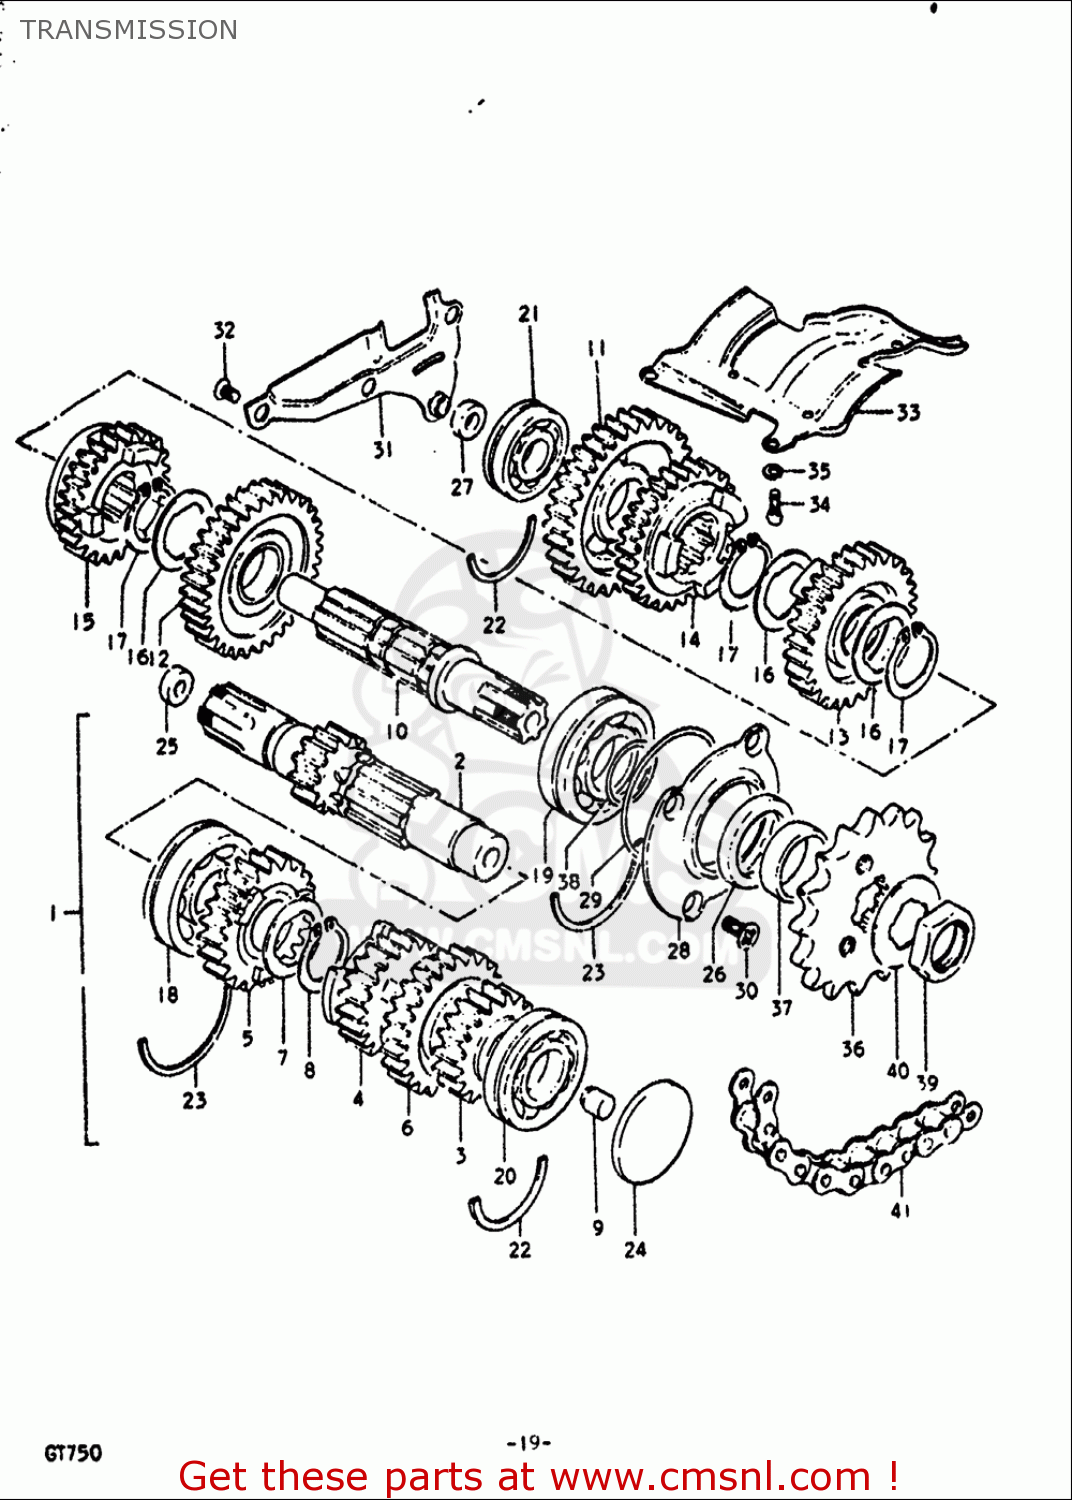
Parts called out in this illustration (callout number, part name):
7	WASHER,LOCK
8	CIRCLIP
9	PLUG
16	WASHER,LOCK
17	CIRCLIP
19	BEARING
20	BEARING(20X47X14)
22	C RING
25	SEAL,OIL (10X17X5)
26	SEAL,OIL(32X42X6)
27	SEAL,OIL(8X14X4)
29	O RING(D:2,ID:64.5)
30	SCREW
32	SCREW
34	SCREW
35	WASHER,LOCK
36	SPROCKET,ENGINE
37	SPACER(25X32X10.7)
38	O RING(D:1,ID:24.5)
39	NUT
40	WASHER,LOCK
